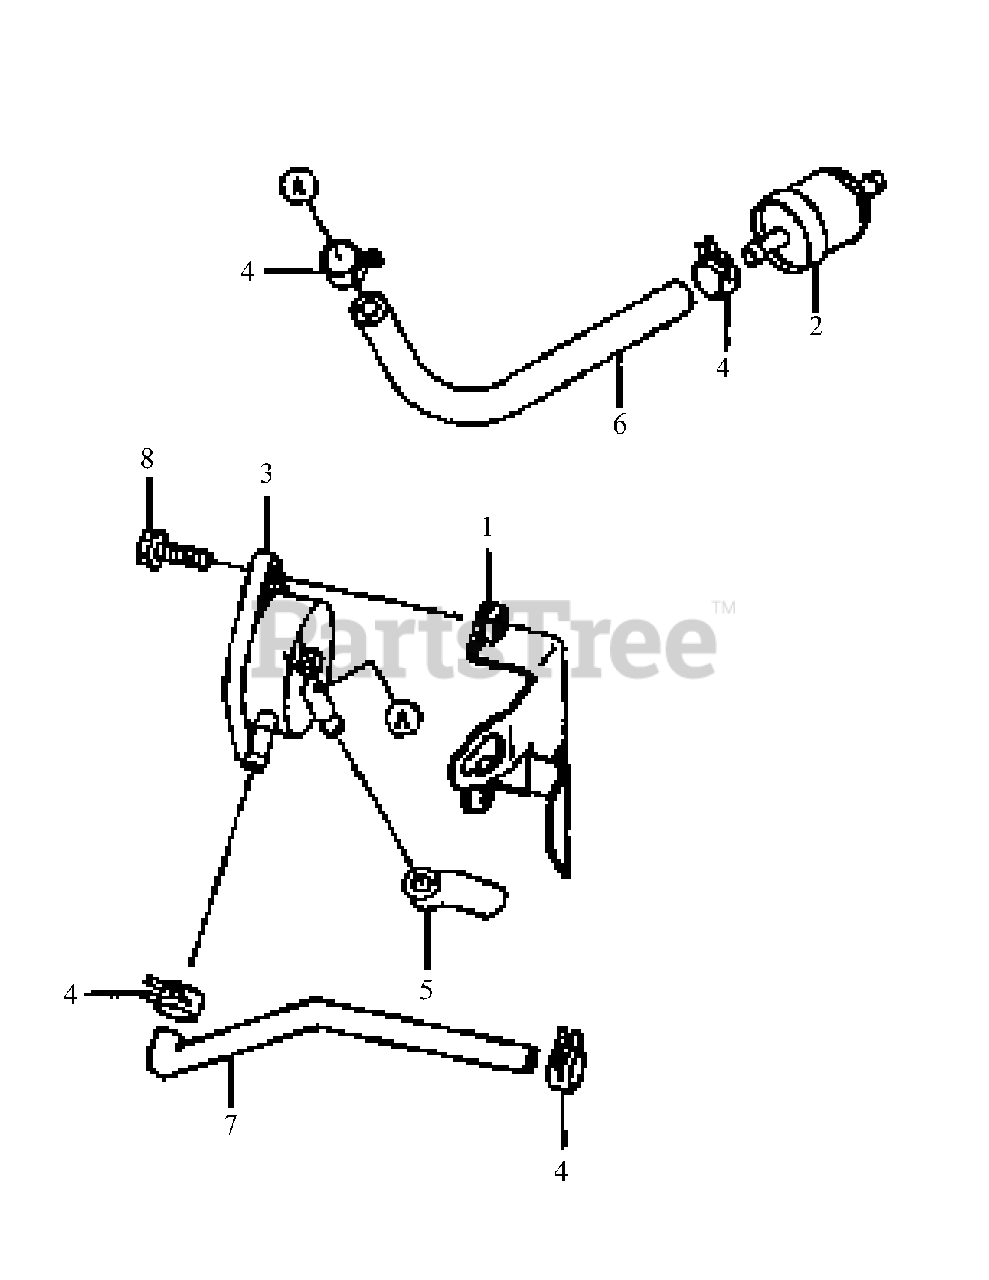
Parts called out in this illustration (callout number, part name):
2	Filter, Fuel
4	Clamp
6	Tube 6.35x12.7x160
8	Bolt, Flange
